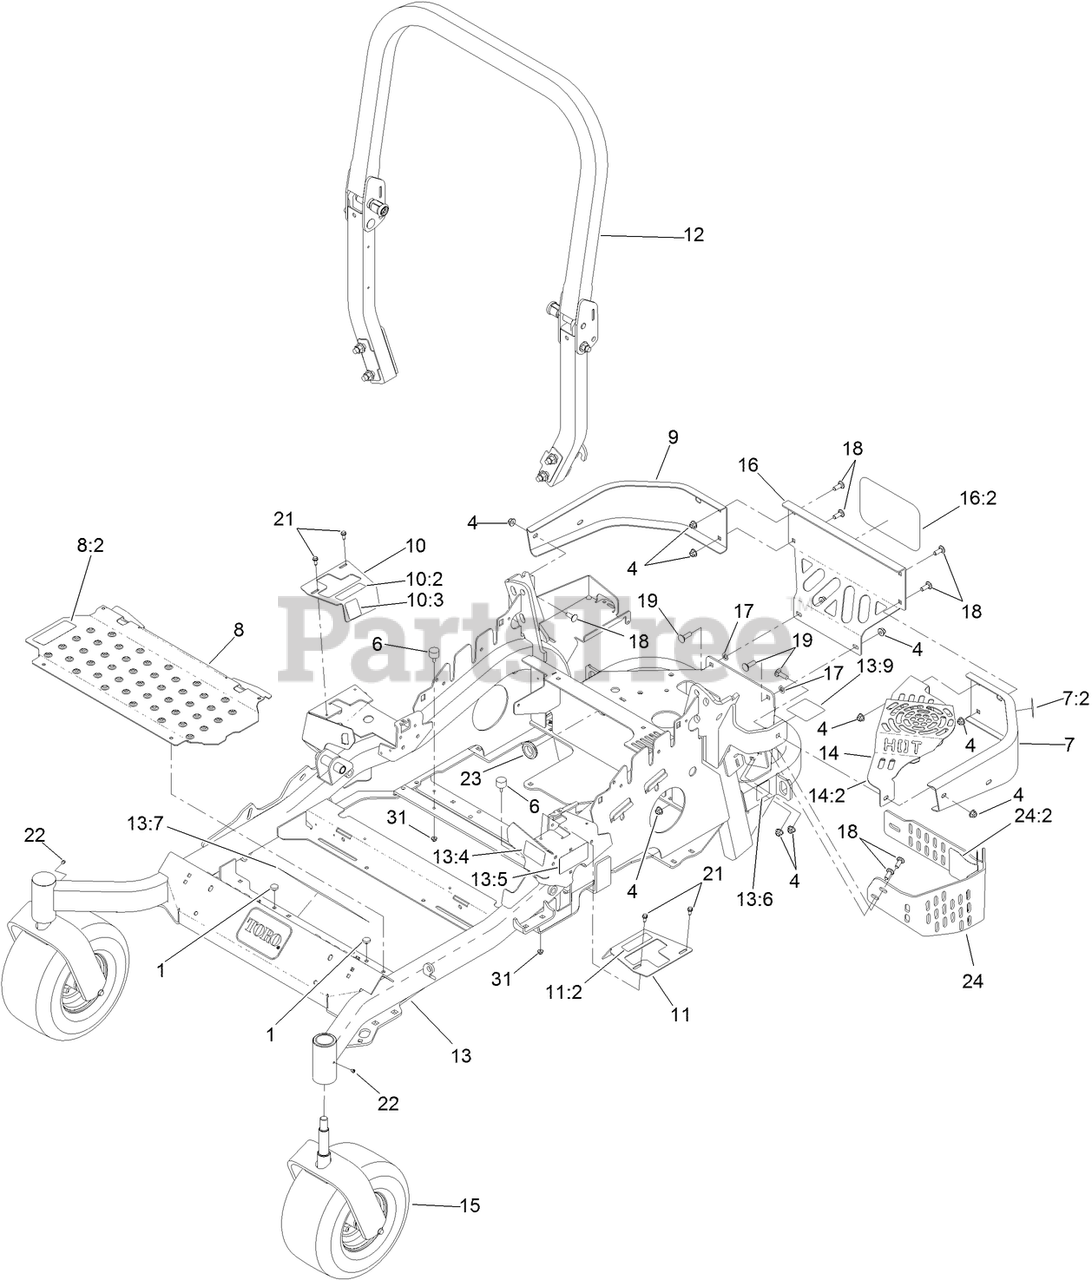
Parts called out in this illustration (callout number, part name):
1	BUMPER
4	NUT-HF, NI
6	BUMPER-RUBBER (W/ STUD)
7	BUMPER-REAR, LH
7:2	DECAL-WARNING
8	FLOORPAN ASM
8:2	DECAL-MISSING, COVER
9	BUMPER-REAR, RH
10	RH MOTION CONTROL COVER ASM
10:2	DECAL-CONTROL, MOTION
10:3	DECAL-PARK BRAKE, CE
11	MOTION CONTROL COVER ASM
11:2	DECAL-CONTROL, MOTION
12	ROPS ASM
13	FRAME ASM
13:4	DECAL-FUEL FILL, CE
13:6	DECAL-HAZARD, PINCHED FINGER
13:7	DECAL-DANGER
13:9	DECAL-BYPASS
14	MUFFLER GUARD ASM W/FOIL
14:2	FOIL-TAPE
15	FRONT CASTER ASM
16	REAR GUARD ASM
16:2	DECAL
17	NUT-PUSH
18	SCREW-CARR
19	BOLT-CARR
21	SCREW-HWH
23	GROMMET
24	LH LOWER MUFFLER GUARD ASM
24:2	DECAL-WARNING
31	NUT-HF
